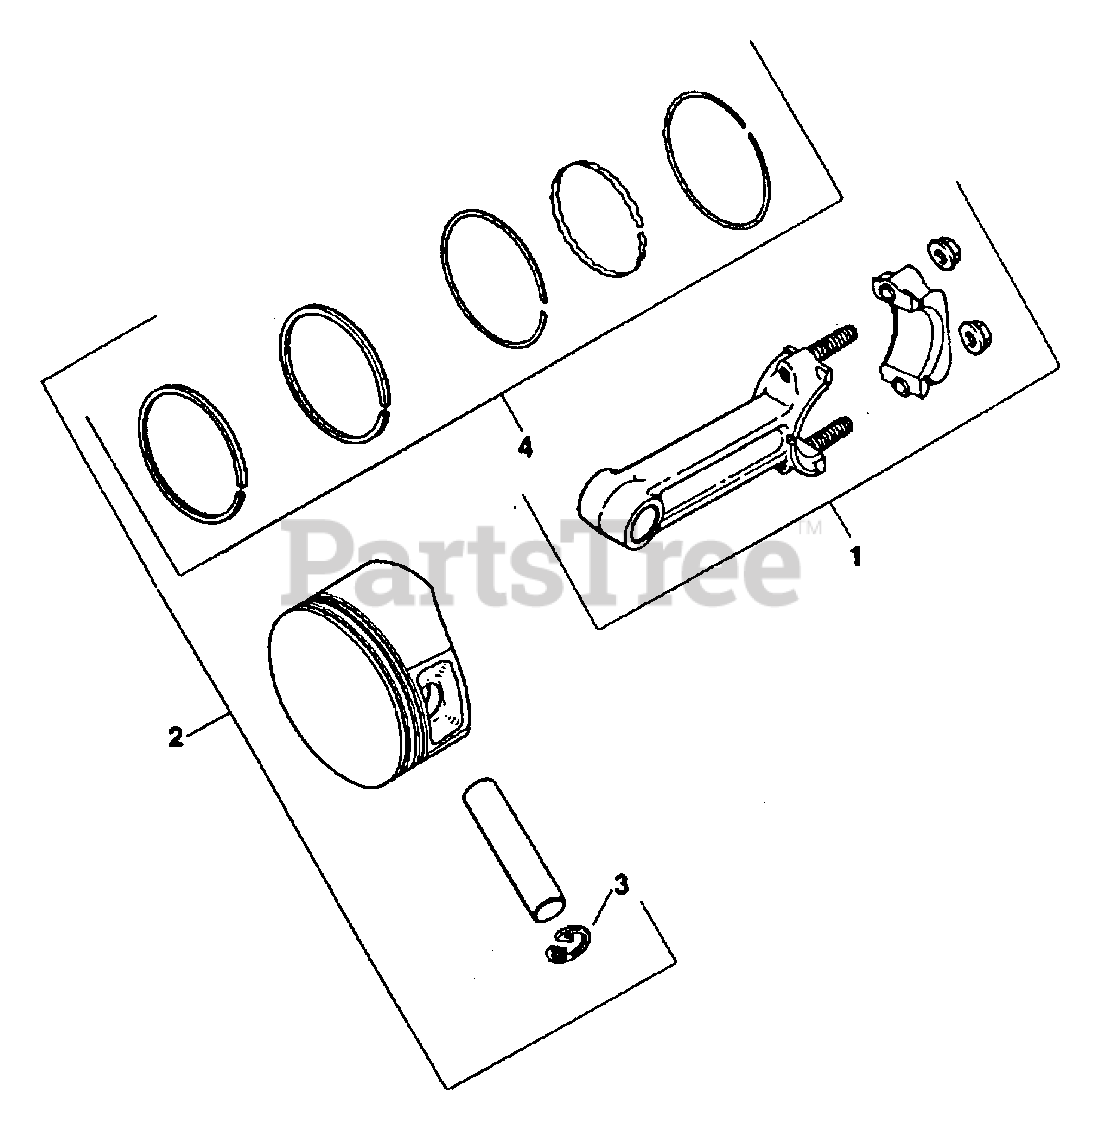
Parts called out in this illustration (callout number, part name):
1	CONNECTING ROD
2	PISTON W/RING SET
3	RETAINER, PISTON PIN
4	RING SET
